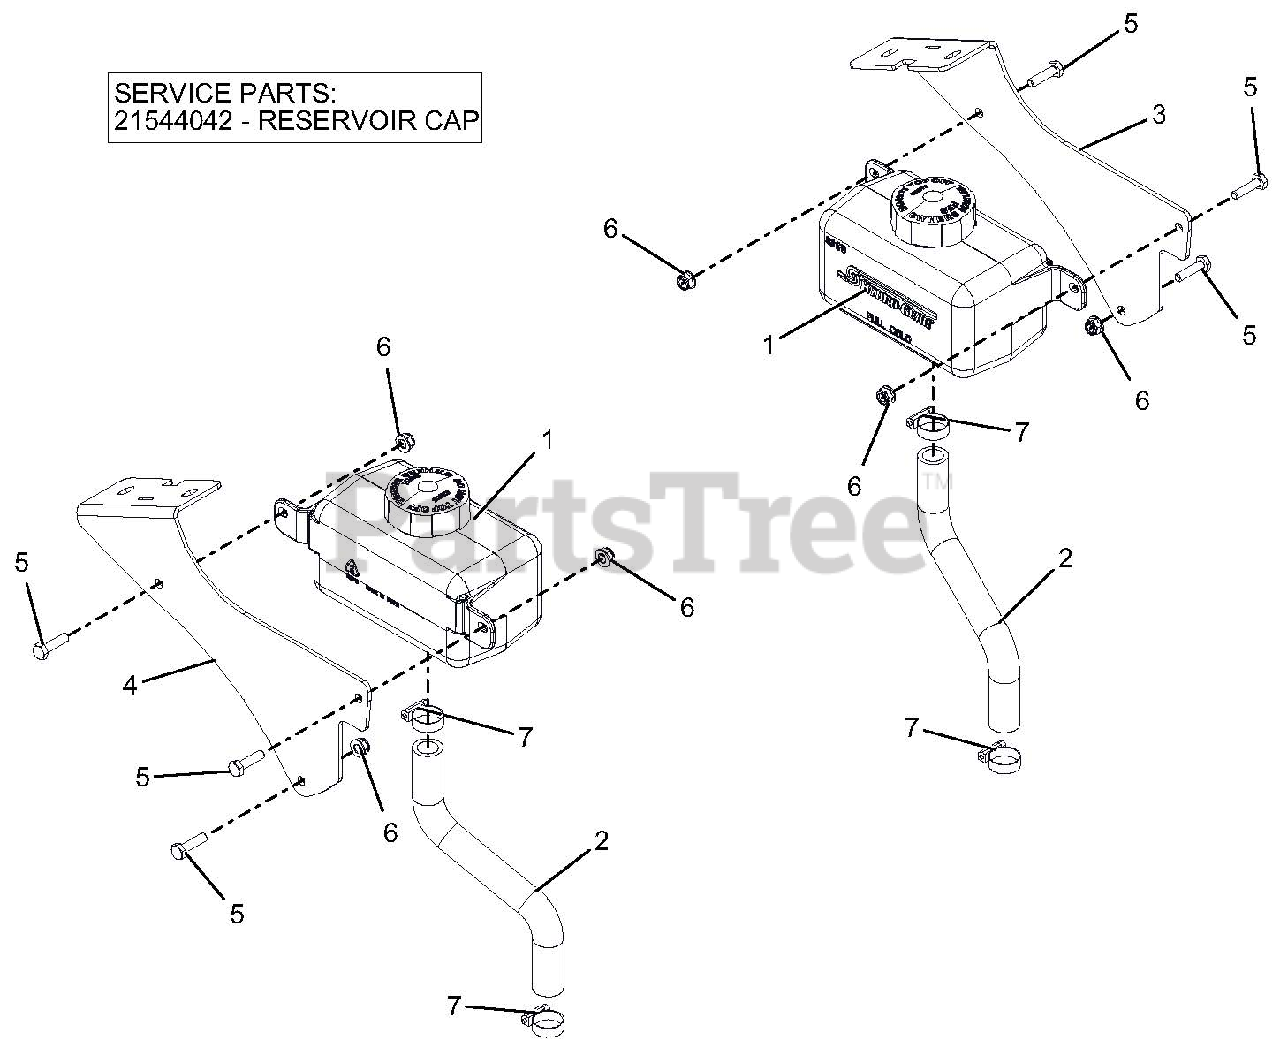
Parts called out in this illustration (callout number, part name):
1	TANK, HYD 1000ML
2	HOSE, HYDRO OVERFLOW
3	BRKT, MTG LH HYDRO
4	BRKT, MTG RH HYDRO
5	BLT-HEX .25-20X1.00 GR5 YWZC
6	NUT-LK-NYL-FLG .25-20 YWZC
7	CLAMP, .88 DIA HOSE
8	RESERVOIR CAP
